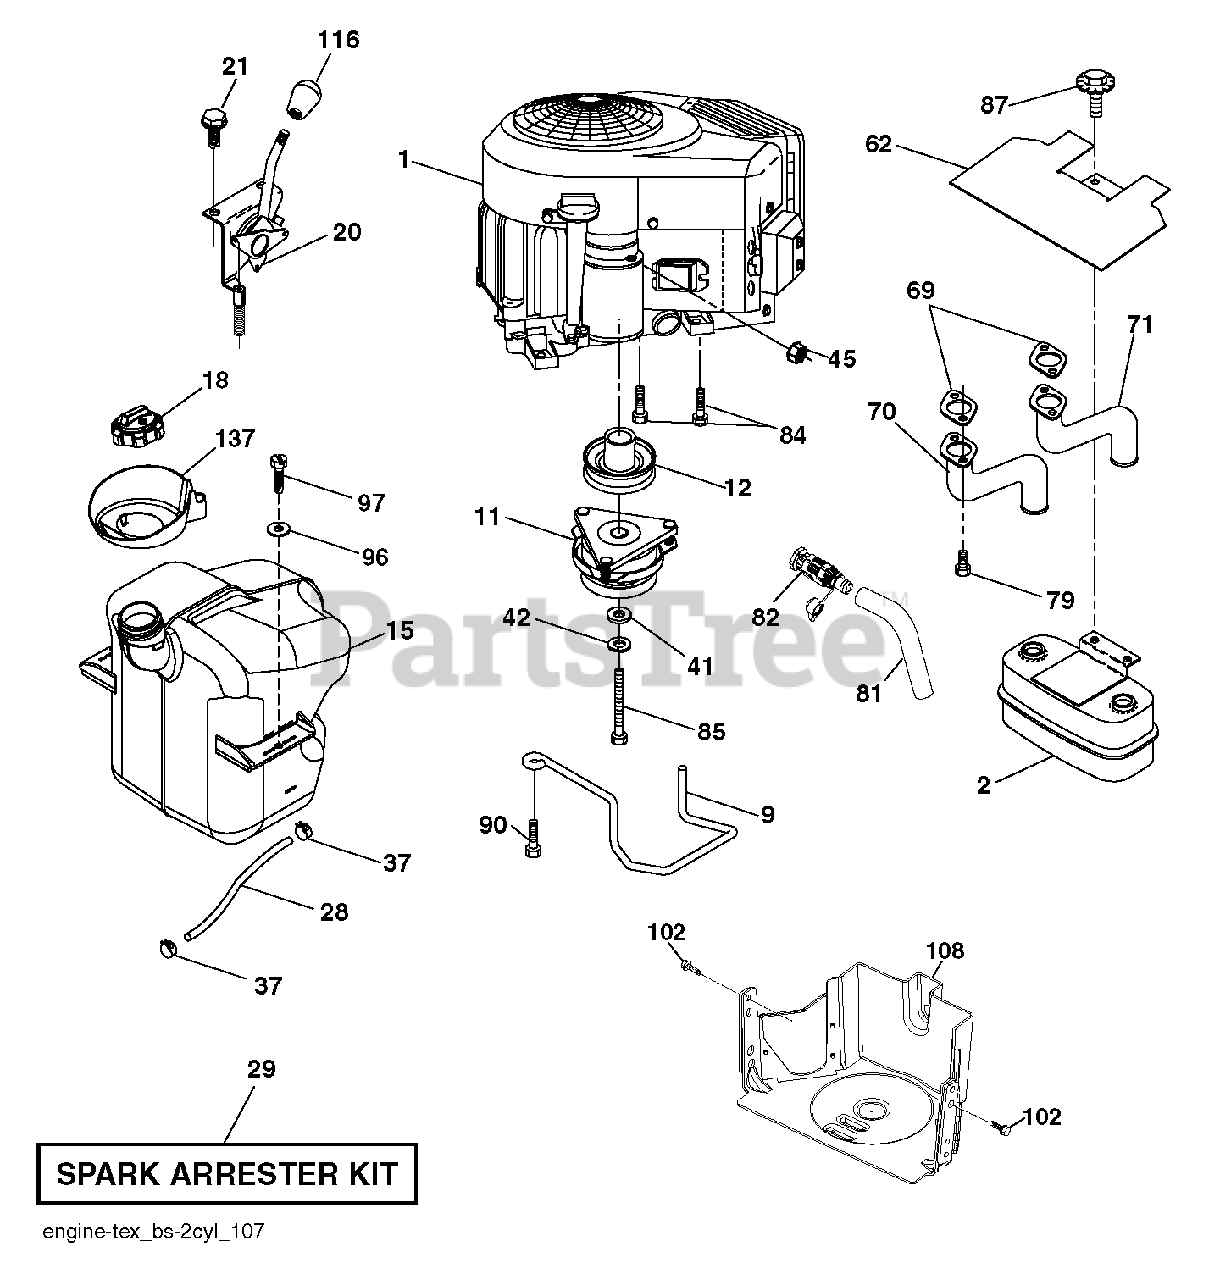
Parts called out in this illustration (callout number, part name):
2	MUFFLER.ASM.TWN.EXTNDED.DFLCTR
9	KEEPER BELT ENGINE
11	CLUTCH.ELECTRIC.LT.48"*
12	PULLEY.ENGINE.TUFFTORQ
15	FUEL TANK TANK. ASSEMBLY. EXTE
18	CAP.ASM.FUEL.2.25"TOP.TURN
20	CONTROL THROTTLE/CHOKE
21	SCREW.#10 X 0.750.BOS
28	LINE.FUEL.20
29	KIT.SPARK ARRESTOR 794945 B&S
37	HOSE CLAMP
42	LOCKWASHER
45	NUT
62	SHIELD.HEAT.MUFFLER
69	GASKET.MUFFLER
70	EXHAUST.TUBE.LH.BS/TWIN
71	EXHAUST.TUBE.RH.B&S.TWIN.INTEK
79	SCREW.SOCKET.HEAD.5/16-18
81	TUBE, DRAIN OIL ASM.
82	VALUE.OIL.DRAIN
84	SCREW.3/8-16
85	BOLT HEX 7/16-20X4-1/4"
87	BOLT, 5/16-18 X 1 3/4
90	SCREW 3/8-16X1
97	SCREW HEXWSHR 1/4-20X3/4
102	SCREW 5/16-18X1
108	COVER PULLEY
116	KNOB - SHIFT
